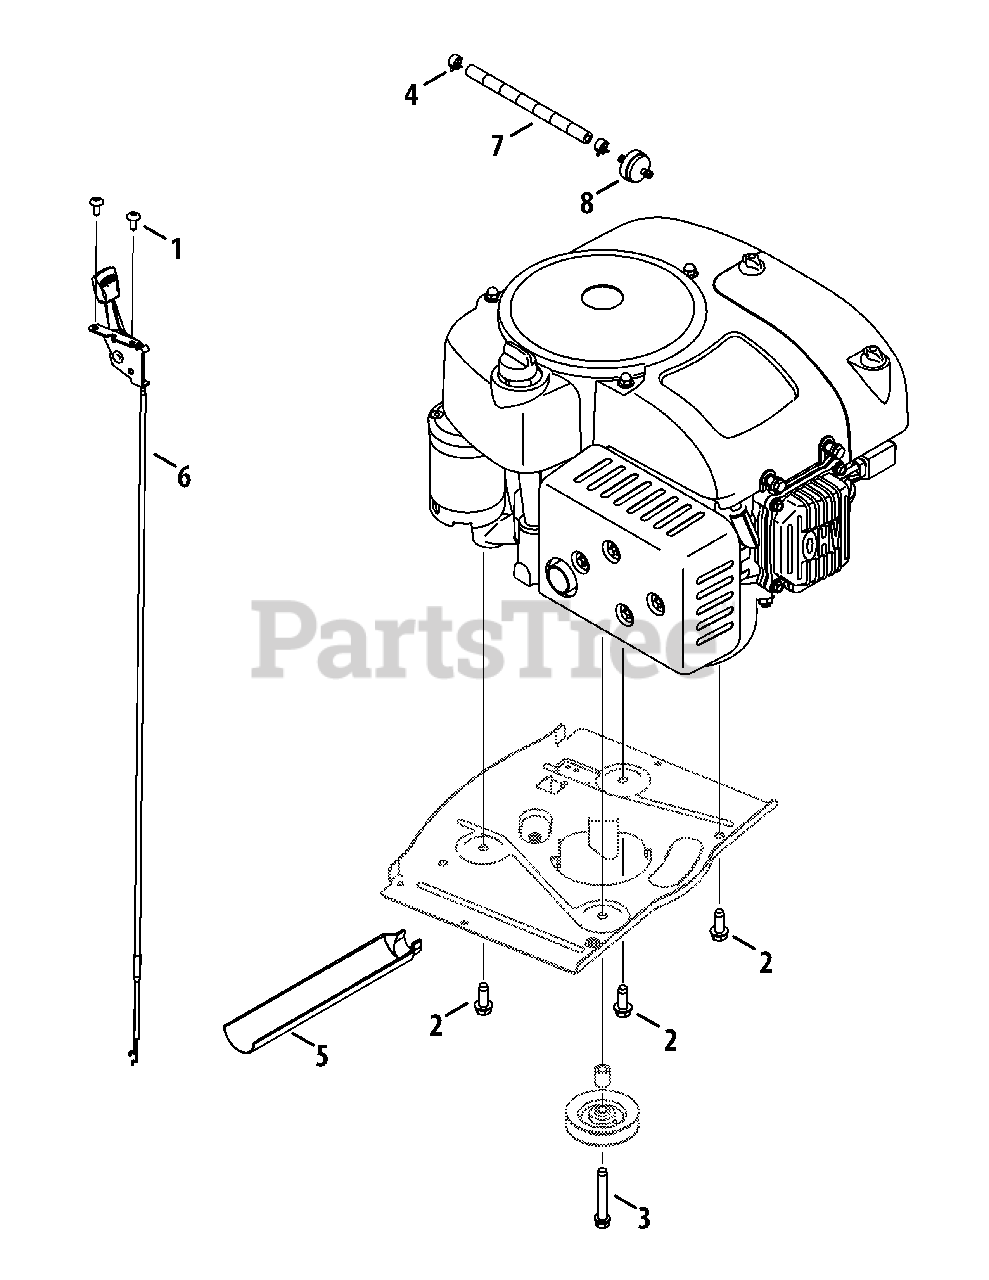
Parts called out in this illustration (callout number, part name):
1	Tap Screw, 1/4-20, 0.500
2	Tap Screw, 3/8-16, 1.000
3	Tap Screw, 3/8-16, 2.250
4	Hose Clamp, .490 DIA.
5	Oil Drain Sleeve
6	Throttle/Choke Cable 31 Lg.
7	Low Permeation Fuel Line, 1/4
8	Fuel Filter
